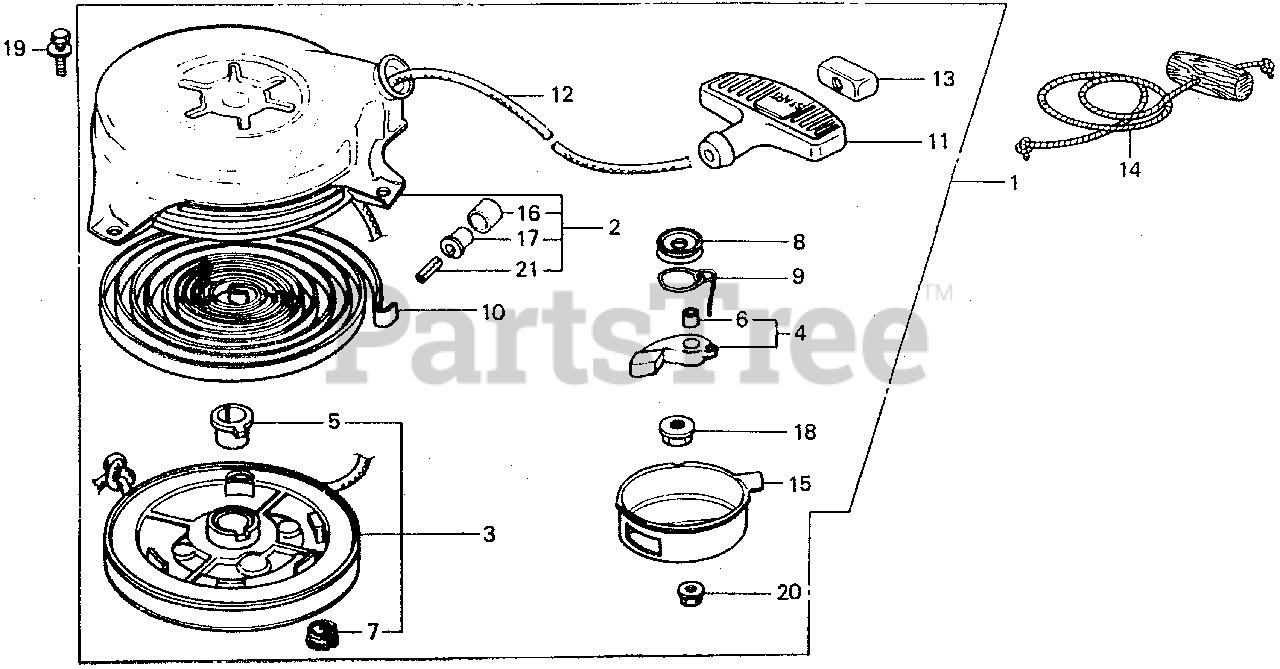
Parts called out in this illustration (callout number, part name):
1	STARTER ASSY., RECOIL *R8* (BRIGHT RED) (NOT AVAILABLE)
2	CASE, STARTER
3	REEL, STARTER
5	BOSS, REEL
6	BUSH, RATCHET
7	BUSH, REEL STARTER
8	PLATE, FRICTION
9	SPRING, FRICTION
10	SPRING, RETURN
11	GRIP, STARTER
12	ROPE, STARTER
13	SUPPORT, GRIP
14	ROPE, STARTER
15	COVER, STARTER REEL
16	ROLLER, GUIDE (NOT AVAILABLE)
17	BUSH, ROLLER
18	NUT, SELF-LOCK (8MM) (CLINCH)
19	BOLT-WASHER (6X10)
20	NUT, FLANGE (5MM)
21	PIN, SPRING (3X18)
